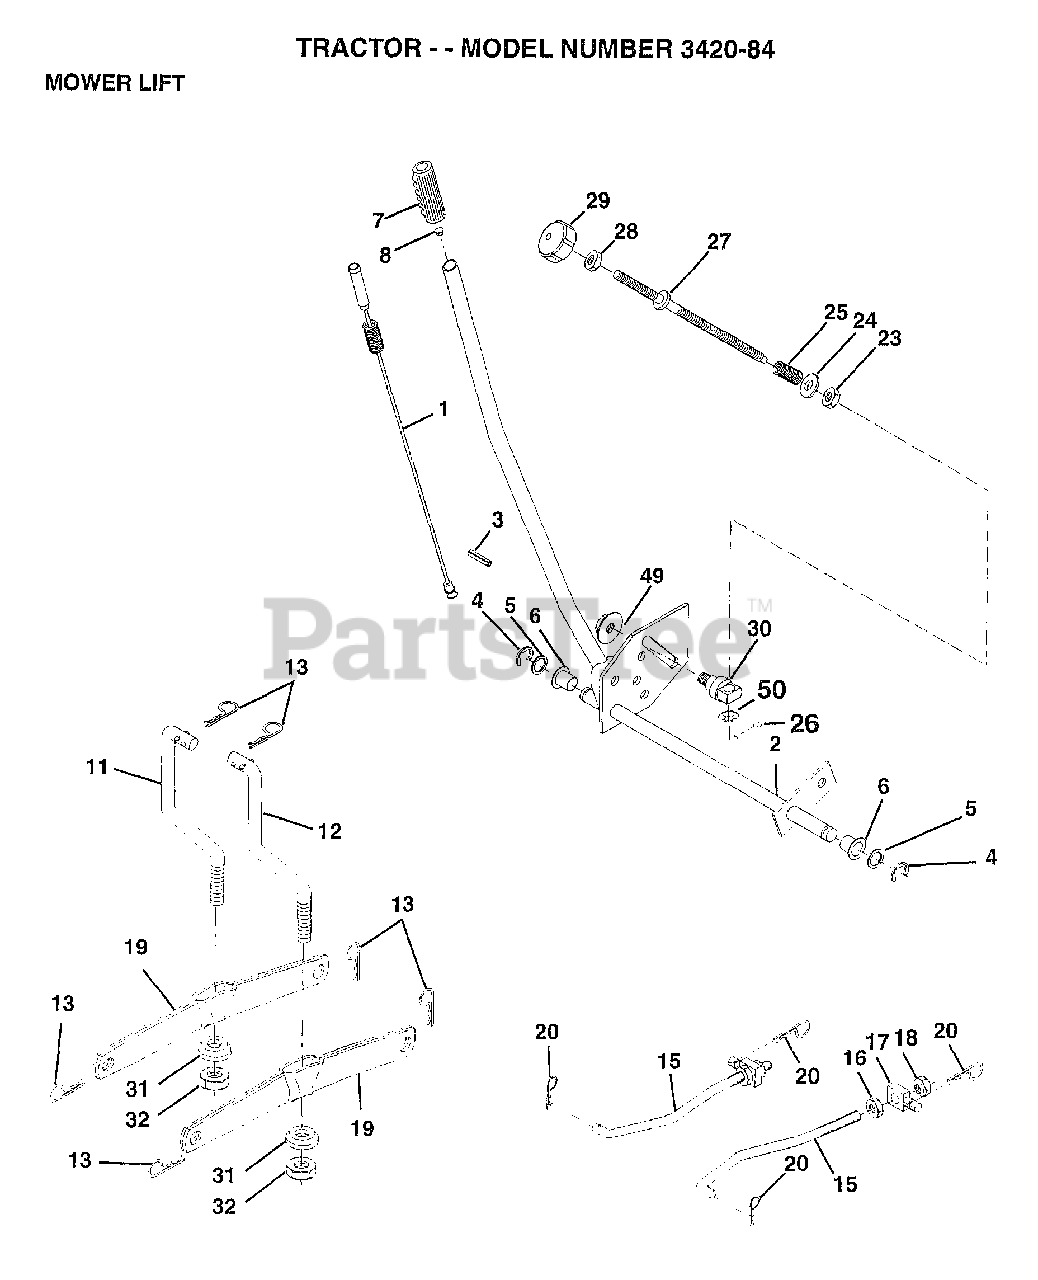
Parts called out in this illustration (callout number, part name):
1	WIRE ASM W.SPRING
2	"SHAFT ASM LIFT,LH"
3	PIN GROOVE
5	WASHER
6	NYLON BEARING
7	GRIP
15	LINK.FRONT
16	NUT
17	TRUNION
18	NUT LTV
19	ARM SUSP REAR
20	RETAINER SPRING
23	NUT T
24	WASHER
25	SPRING.COMP.INF.H
27	ROD.ADJ.LIFT
28	NUT
29	KNOB INF 3/8-16
30	TRUNNION
31	BEARING PVT LH
32	NUT.CROWNLOCK.3/8
49	NUT.HXFLG.LOCK.
